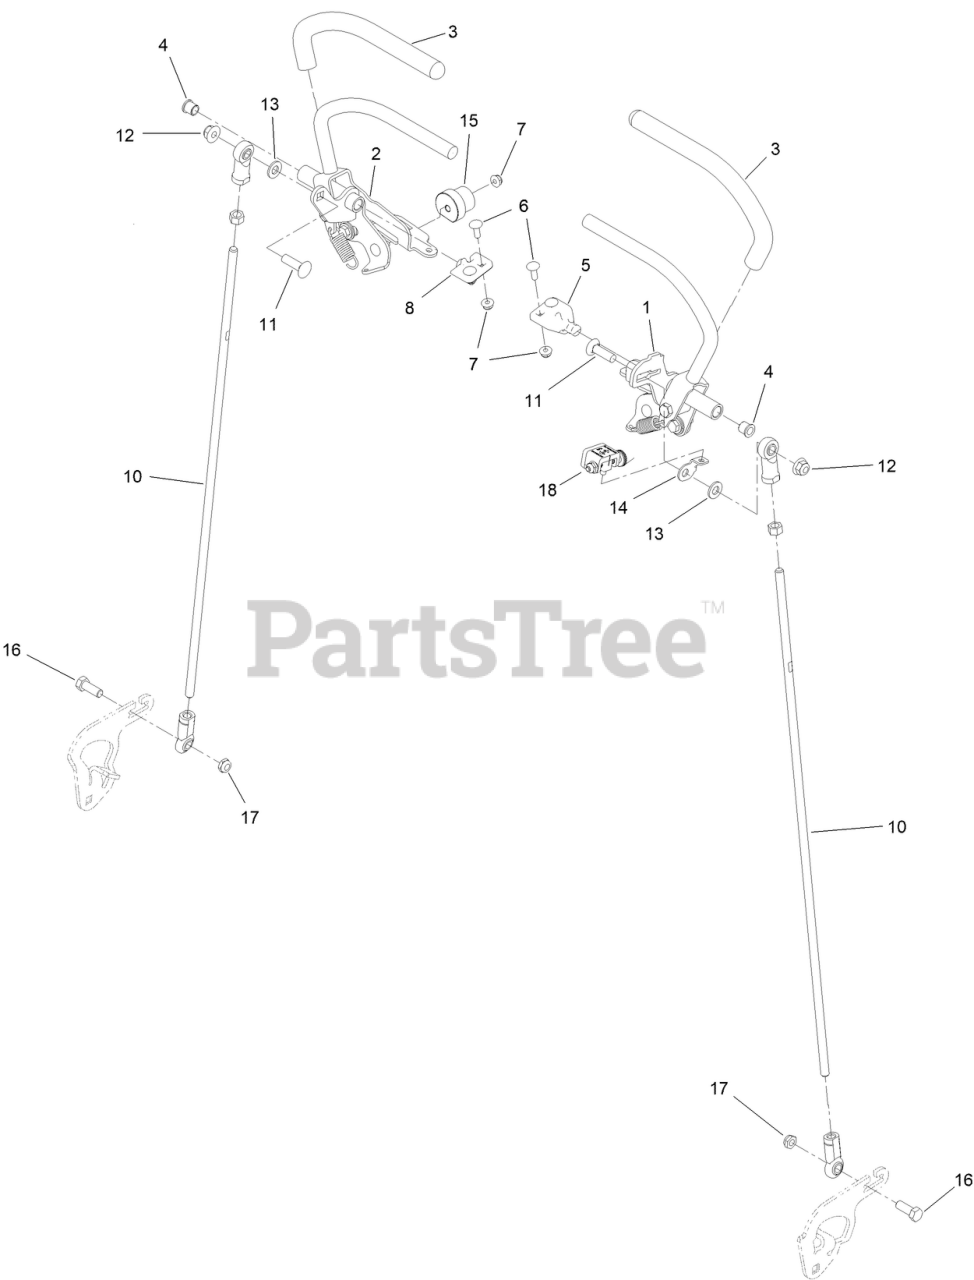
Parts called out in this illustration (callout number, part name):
1	LH CONTROL HANDLE ASM
2	RH CONTROL HANDLE ASM
4	BEARING
5	TAB-PIVOT, LH
6	BOLT-CARR
7	NUT-HF
8	TAB-PIVOT, RH
10	RH CONTROL ROD ASM
11	SCREW-CARR
12	NUT-HF, NI
13	WASHER-FLAT
14	BRACKET-ADJUSTMENT, SPEED
16	SCREW-HH
18	SPEED SETTING TOOL
